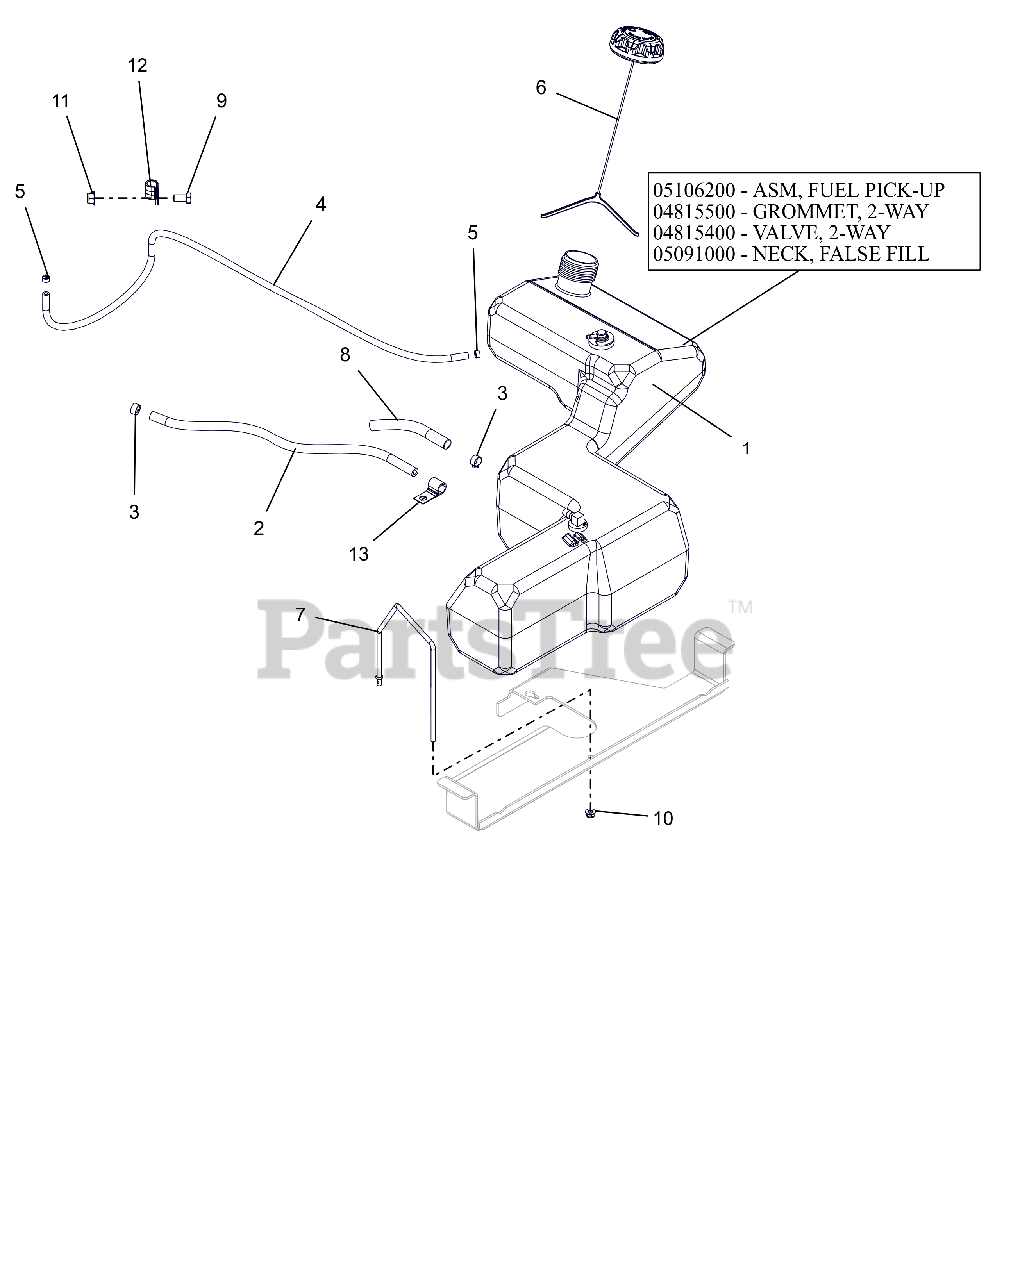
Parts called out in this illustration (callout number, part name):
1	ASSY, FUEL TANK-IKON
1	ASM, IKON FUEL PICK-UP
1	GROMMET, 2-WAY
1	VALVE, 2-WAY
1	NECK, FALSE FILL-2017 IKON
2	HOSE, .25 LOW-PERM BULK GAS
3	CLAMP, FUEL LINE
4	HOSE, .188 LOW-PERM BULK GAS
5	CLAMP-HOSE, SPRING .188
6	CAP, FUEL VENT-IN 2.25" RATCH.
7	BRKT, FUEL TANK HOLD DOWN
8	WRAP, ANTIABRASION .5X.064WALL
9	@BLT-HEX .38-16X.75 GR5 YWZC
10	@NUT-LK-NYL-FLG .25-20 YWZC
11	@NUT-LK-NYL-FLG .38-16 YWZC
12	CLAMP, CUSHIONED STEEL
13	J-CLAMP
